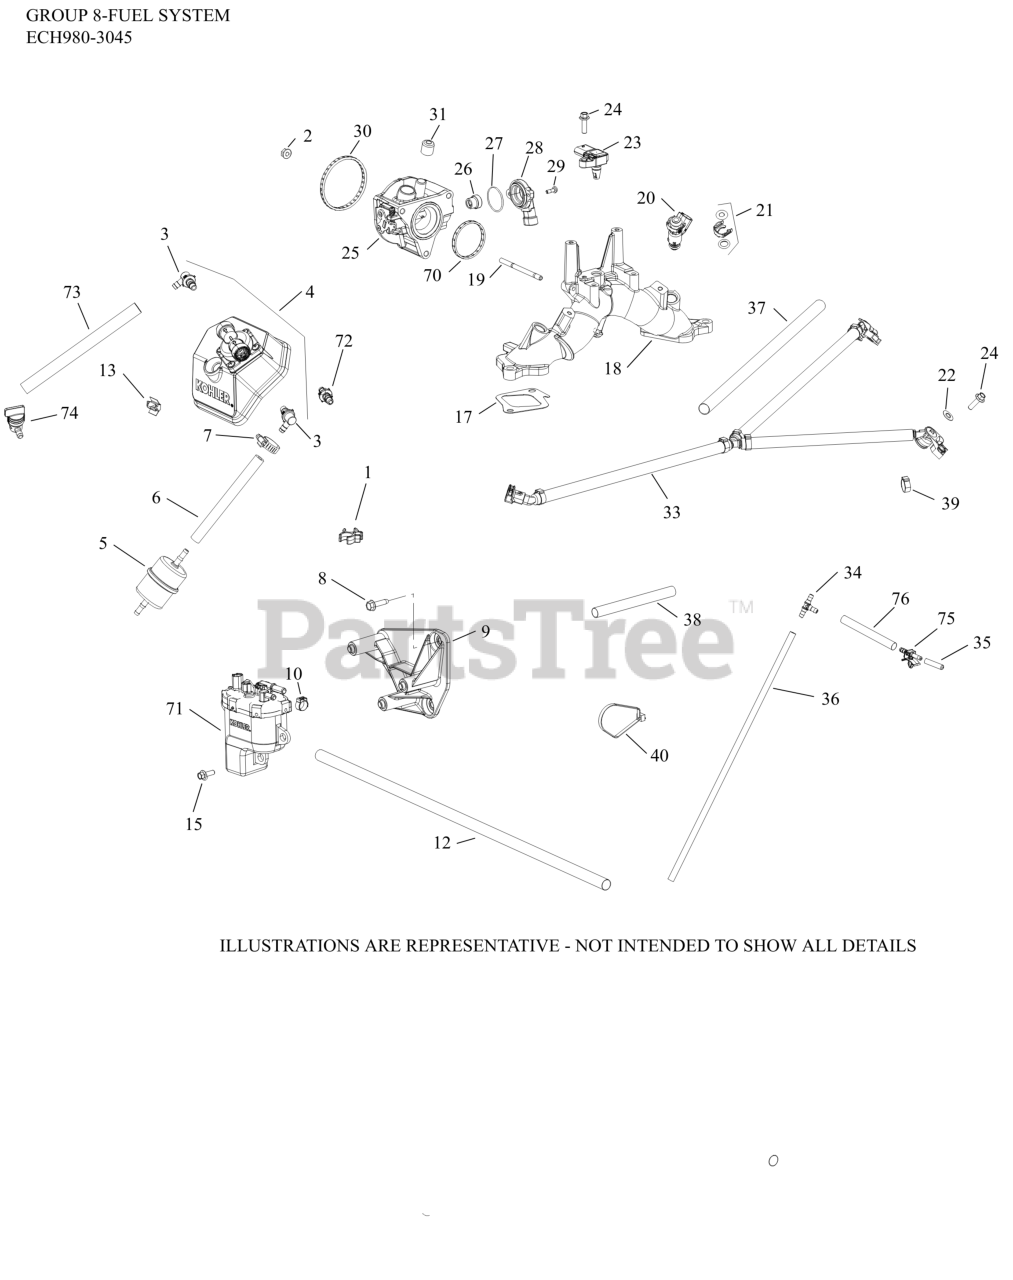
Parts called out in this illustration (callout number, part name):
1	RETAINER, HOSE
2	NUT, FLG M6X1.0
3	KIT, 90 DEG. FITTING
4	KIT, FUEL PUMP
5	FILTER, FUEL
6	HOSE,LW PERM.FUEL 24.00"-USE 25 111 81-S
7	CLAMP, HOSE (KM)-USE 25 237 31-S
8	SCREW, THREAD FORMING
9	BAFFLE, FUEL PUMP MODULE (HORZ)
10	CLAMP, OETIKER
12	SLEEVE, ANTI ABRASION
13	CLIP, O2 SENSOR
15	SCREW, FLG M6X1.0X16
17	GASKET, INTAKE MANIFOLD
18	MANIFOLD, INTAKE HORIZONTAL (EFI)
19	STUD,M6X1.0X84
20	INJECTOR, FUEL
21	KIT, FUEL INJECTOR O-RING
22	CLIP, RETAINER
23	SENSOR, T-MAP
24	SCREW, FLG M6x1.0x20
25	BODY, THROTTLE ASM (34)
26	MAGNET ASSEMBLY, TPS
27	O-RING, TPS SENSOR
28	SENSOR, THROTTLE POSITION
30	O-RING (HDAC SEAL-EFI)
31	CAP, MASKING
33	RAIL ASSEMBLY, FUEL (HORZ)
34	TEE CONNECTOR
35	CAP, MASKING
36	HOSE, EVAPORATIVE
37	SLEEVE, ANTI ABRASION
38	SLEEVE, ANTI ABRASION -USE 25 431 12-S
39	CLAMP, HOSE
61	FILTER,FUEL 75 MICRON (GRAVTY FEED)
70	O-RING, THROTTLE BODY
71	KIT, FUEL PUMP MODULE
72	KIT, STRAIGHT FITTING
73	SLEEVE, ANTI ABRASION-USE 25 431 12-S
74	VALVE, FUEL SHUT-OFF
75	CONNECTOR, EVAPORATIVE
76	SLEEVE, ANTI-ABRASION
